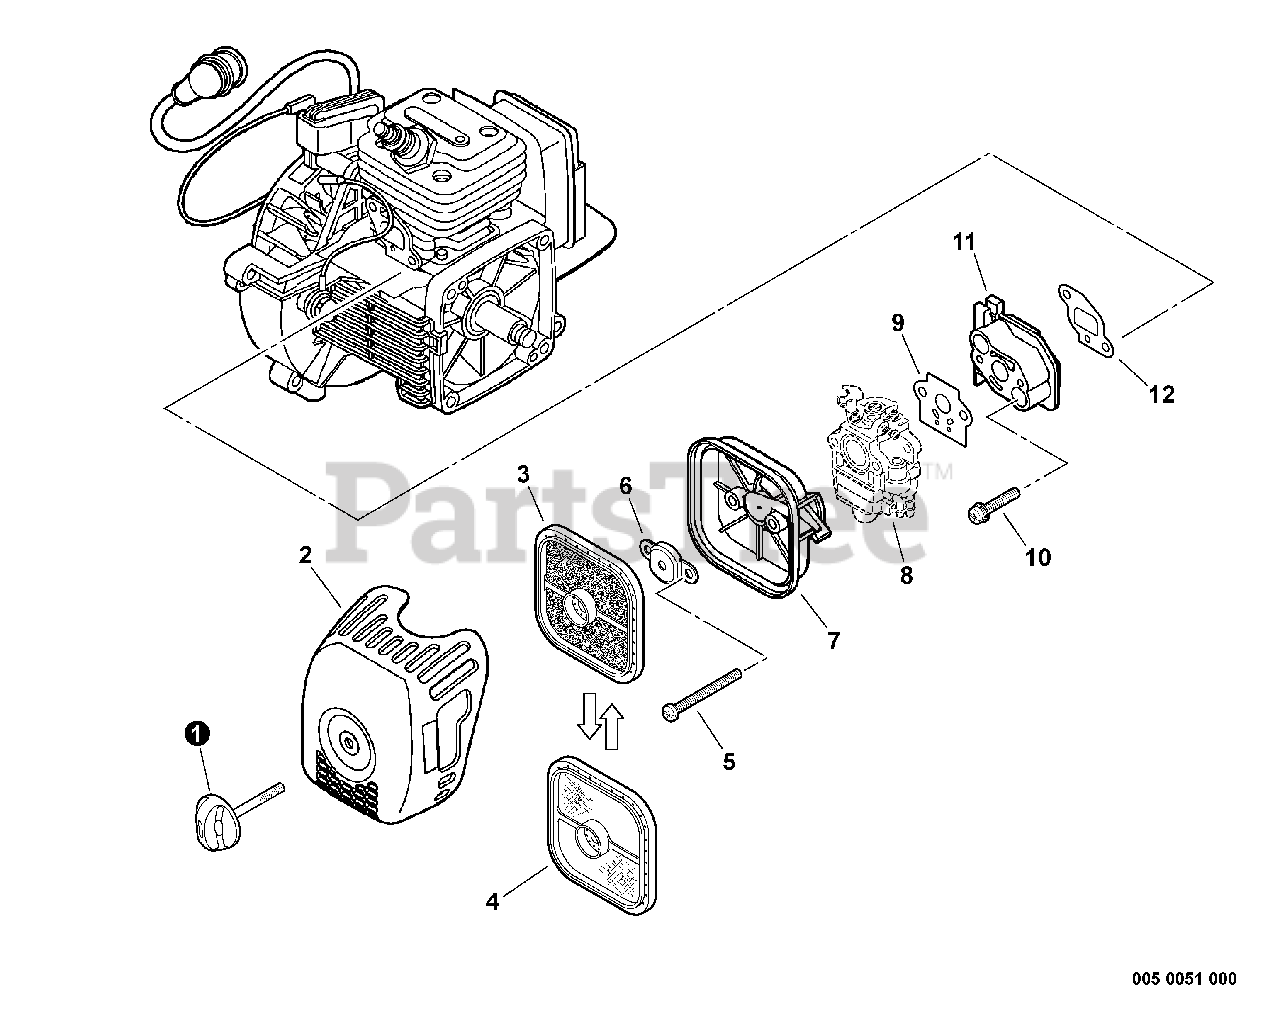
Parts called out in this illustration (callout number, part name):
1	THUMBSCREW
2	COVER, AIR FILTER
3	FILTER, AIR - DOUBLE LAYER
4	FILTER, AIR - SINGLE LAYER
5	SCREW 5×60
6	PLATE, PREVENT
7	CASE, AIR FILTER
8	CARBURETOR
9	GASKET, INTAKE
10	BOLT 5×30
11	INSULATOR, INTAKE
12	GASKET, INTAKE
